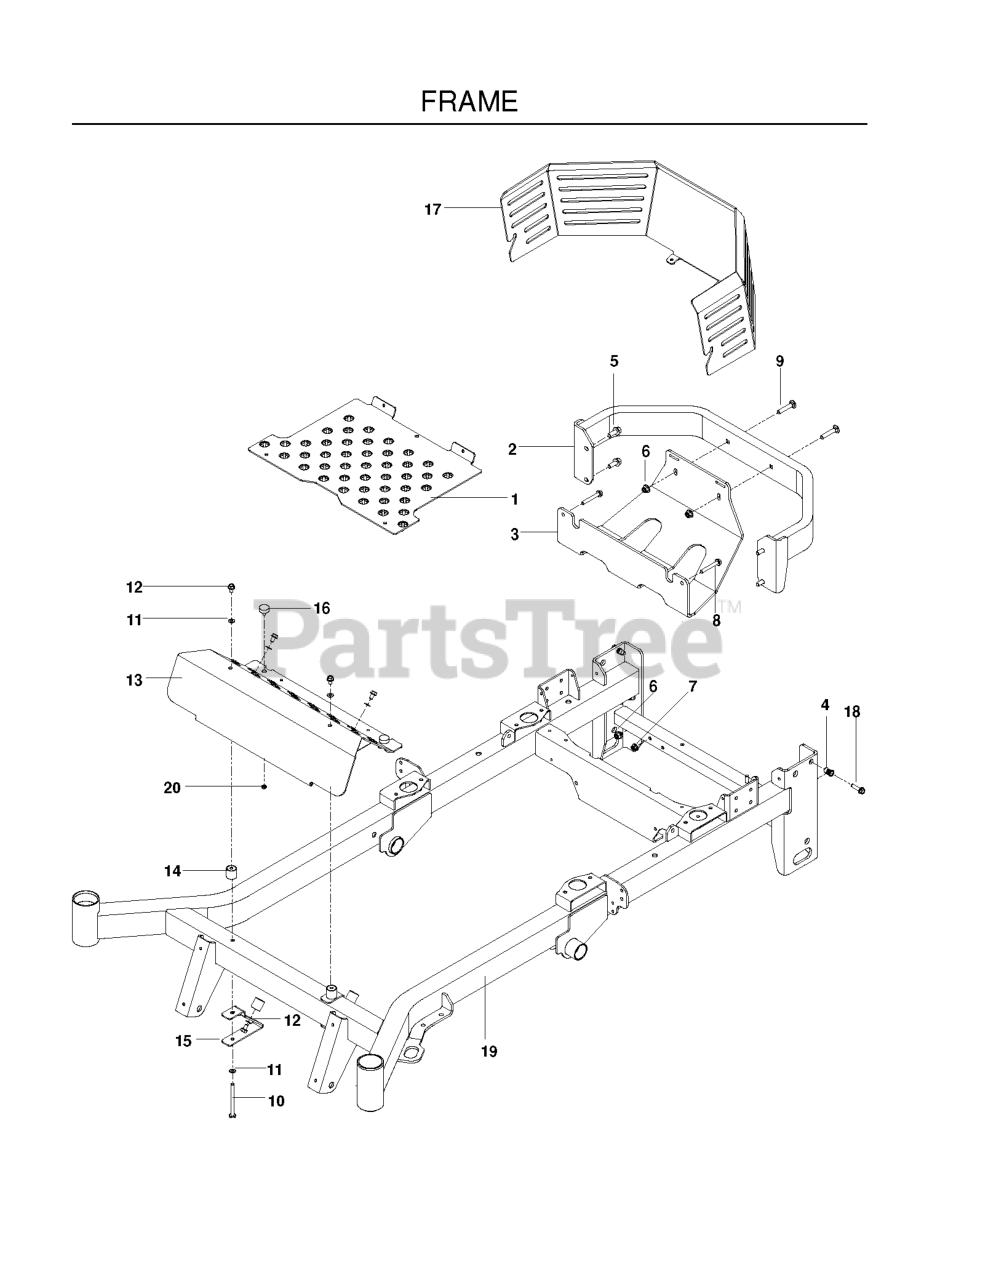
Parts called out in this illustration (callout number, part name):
1	PLATE, FLOOR PAN, BLUE
2	BUMPER, REAR, BLUE
3	PLATE, SKID, BLACK
4	NUTSERT 5/16-18 THICK GRIP
5	HHFS 3/8-16 X 1 GRD 5 ZD
6	NUT 3/8-16 HEX FLG NYLOC ZD
7	5/16-18 NYLOC FLANGE NUT
8	HHFS 5/16-18 X 2.25 GD 5
9	RHSNB 3/8C X 2
10	HHFS 5/16-18 X 3 3/4
11	WASH 5/16 DISC SPRING ZD
12	SCR 5/16-18 X 1/2 SELFTAP ZN
13	PLATE, FOOTREST, BLUE
14	MOUNT, F/F INSERT
15	BRACKET, REST MOUNT
16	BUMPER, 1/4-20 STUD, 1/4
17	GUARD, REAR, BLUE
18	HHFS 5/16-18 X 1.25 TPBLT GD 5
19	FRAME W/DECALS, GARIZZLY SE
20	JAM NUT 1/4C
